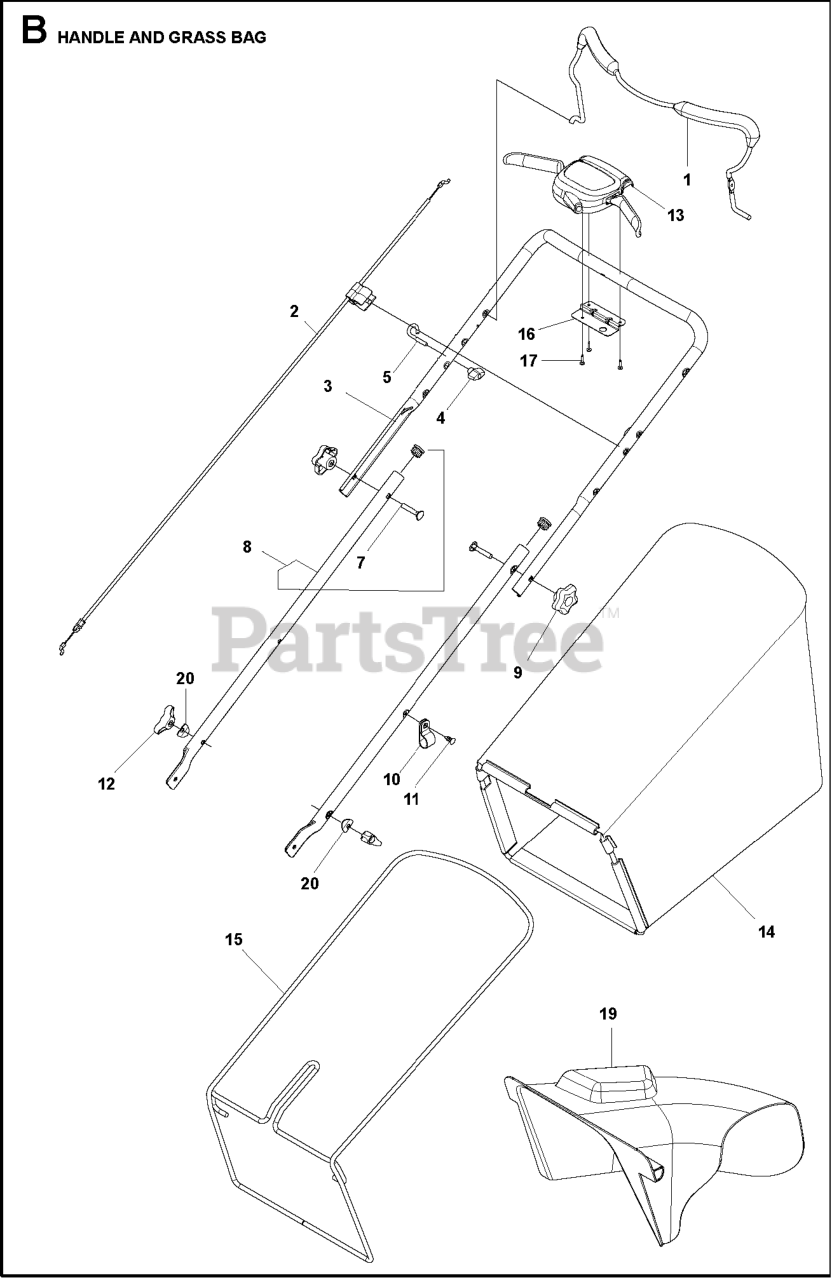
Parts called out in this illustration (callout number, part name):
1	BAIL.OM.ERGO.BENT.MZR.ORAN.668
2	CABLE.MZR.ZONE.CONTROL
3	HANDLE.UPPER.3.POS.BS.AW2.GREY
4	T-KNOB.NEW ROPE GUIDE
5	GUIDE.ROPE.BLK.ZINC.CHROM
7	BOLT.CONCAVE.HEAD.RETAINING
8	HANDLEBAR ASSY TWO PIECE LOWER
9	KNOB.HANDLE.PLASTIC.STAR.BLACK
10	CLIP.CABLE.BLK
11	FASTENER.PUSH.O.250X0.783
12	KNOB, DEFLECTOR
13	DRIVE CABLE 21 EFF DUAL TRIGGE
14	GBAG.C361029EM.HUSQ.GRY.21EFF
15	FRAME.GBAG.AWD.21.BLACK
16	BRACKET DUAL TRIGGER CONTROL
17	SCREW, PHILLIPS HEAD 10 X 5/8
19	CHUTE.DISCHARGE.21EFF.HW
20	WASHER CURVED 5/16"X1"X0.06" S
